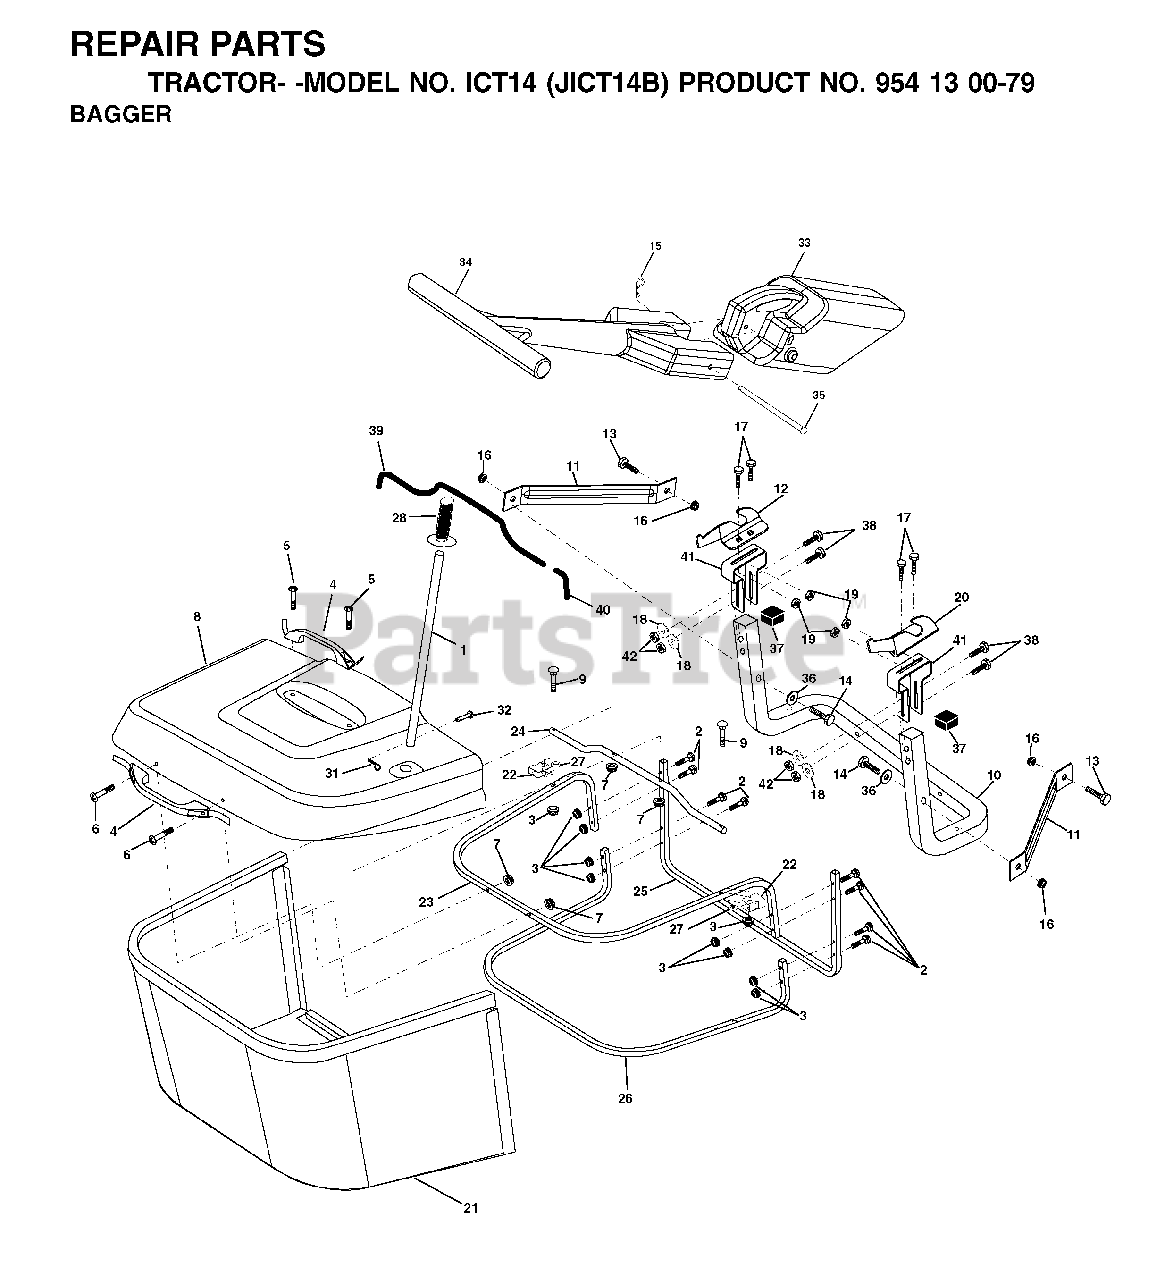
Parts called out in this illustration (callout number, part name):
1	TUBE HANDLE BAGGER
3	NUT T
5	SCREW.PAN.HEAD
10	TUBE
11	BRACKET
14	BOLT-HEX EAK
15	RETAINER-SPRNG RB
16	NUT LOCK FLG 3/8-16 UNC
17	BOLT
18	WASHER M
19	NUT LOCK HEX FLANGE 5/16-18
20	BRACKET
21	BAG
22	BRACKET
23	TUBE
24	TUBE
26	TUBE
31	RETAINER M
32	RIVET,DRILLED
33	PLUG
35	PIN
36	WASHER
38	BOLT.5/16-18X2.5
39	TRIM
40	TRIM
41	BRKT, BAGGER
42	NUT.71038.31-18.HEX.NYLOCK
